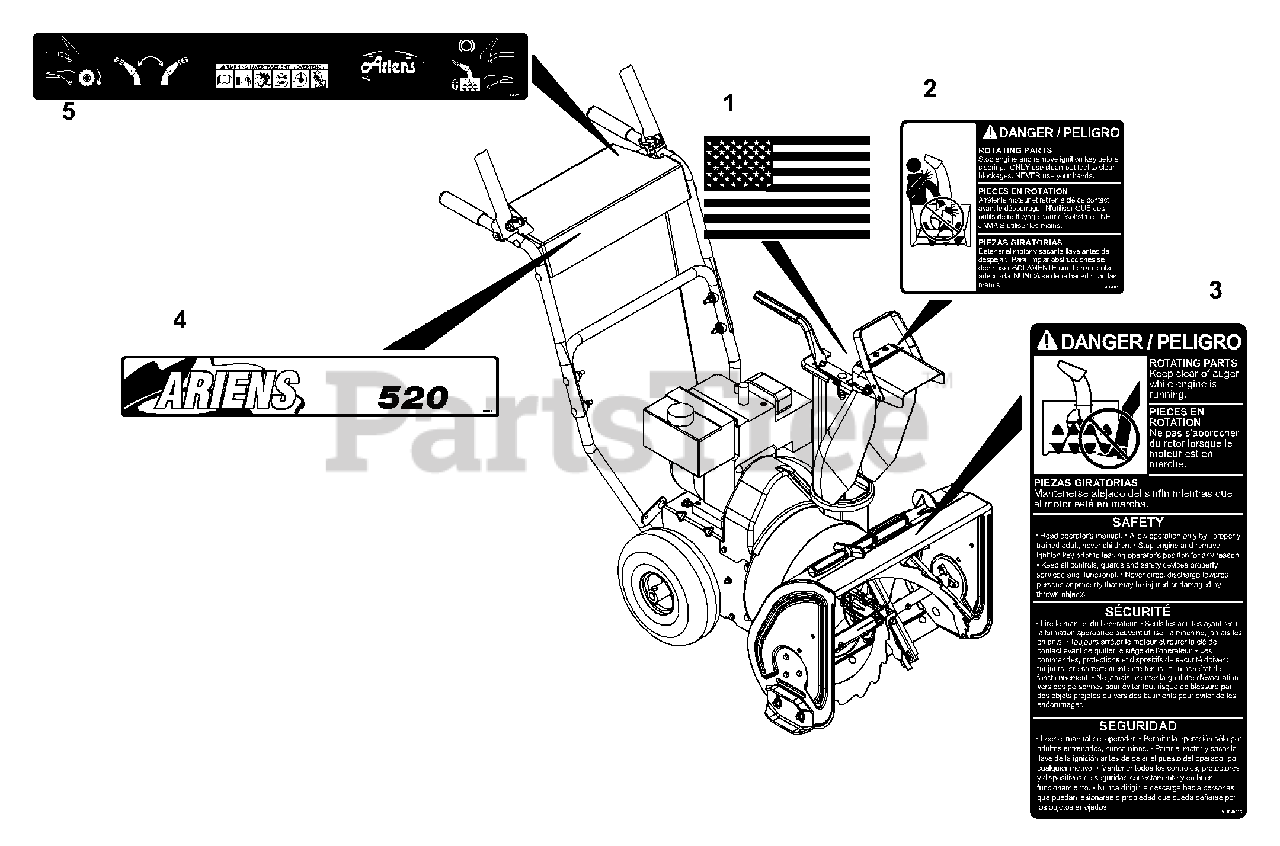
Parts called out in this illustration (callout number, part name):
1	DECAL, AMERICAN FLAG
2	DECAL, DANGER - ROT. PARTS
3	DECAL, DANGER
4	DECAL, FRONT PANEL, 520
5	DECAL, CTRL PANEL, SINGLE SPD
